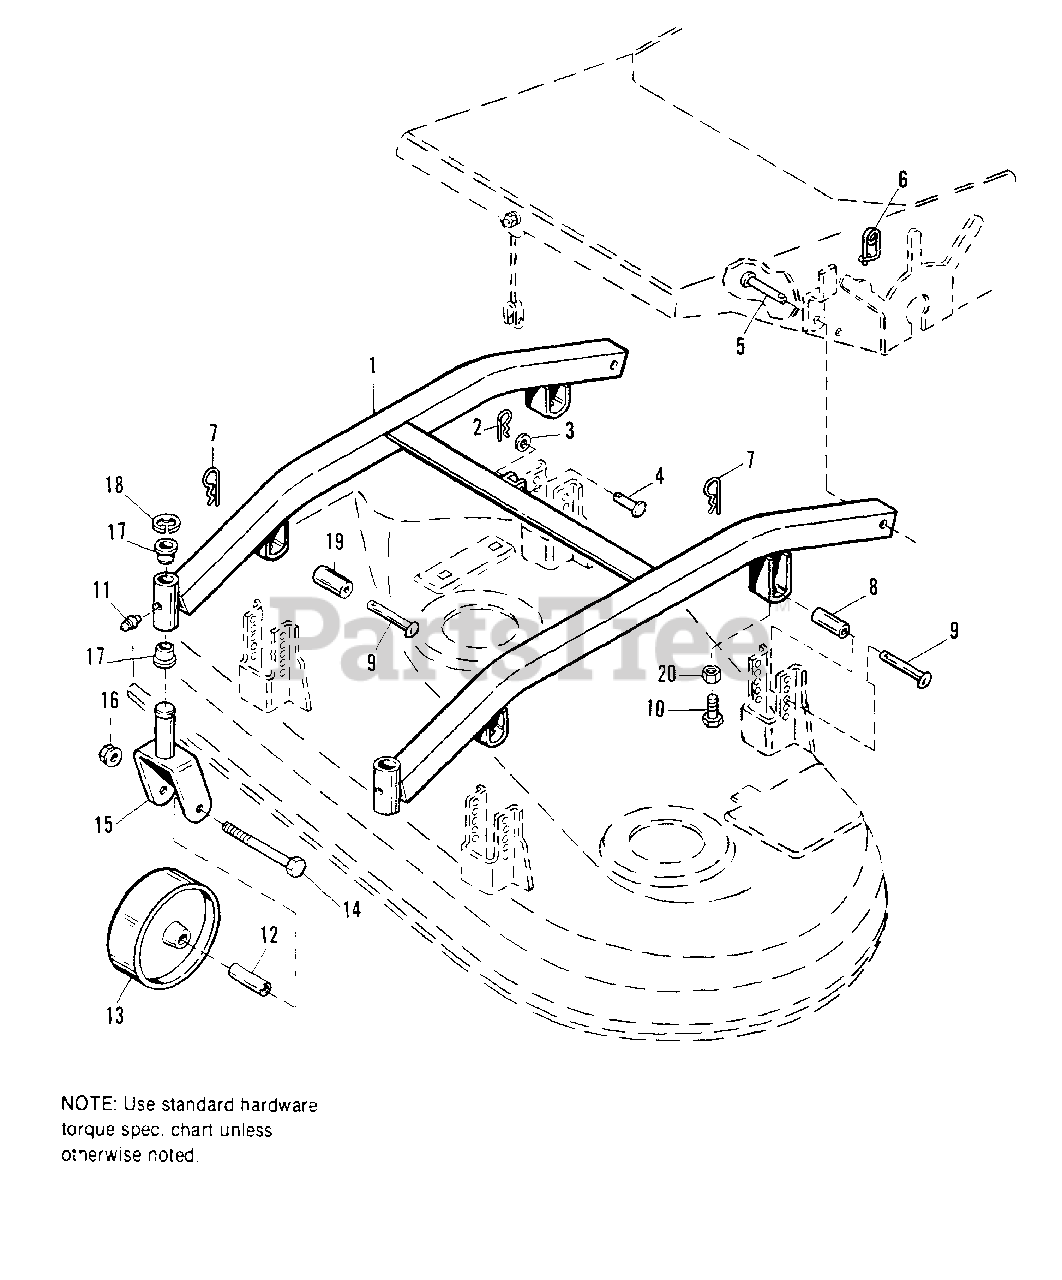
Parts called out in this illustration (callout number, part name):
1	SUPPORT ASSY., 36" Mower
2	PIN, Quick
3	WASHER, 1/4
4	PIN, Lift Cable
6	PIN, Safety
7	PIN, Quick
8	SPACER, Rear
10	CAPSCREW, Hex Hd., 3/8-16 x 1
11	FITTING, Lube
12	SPACER, Wheel
14	CAPSCREW, Hex Hd., 1/2-13 x 3-1/2
16	LOCKNUT, 1/2-13
19	SPACER, Front
20	NUT Hex Jam, 3/8-16
